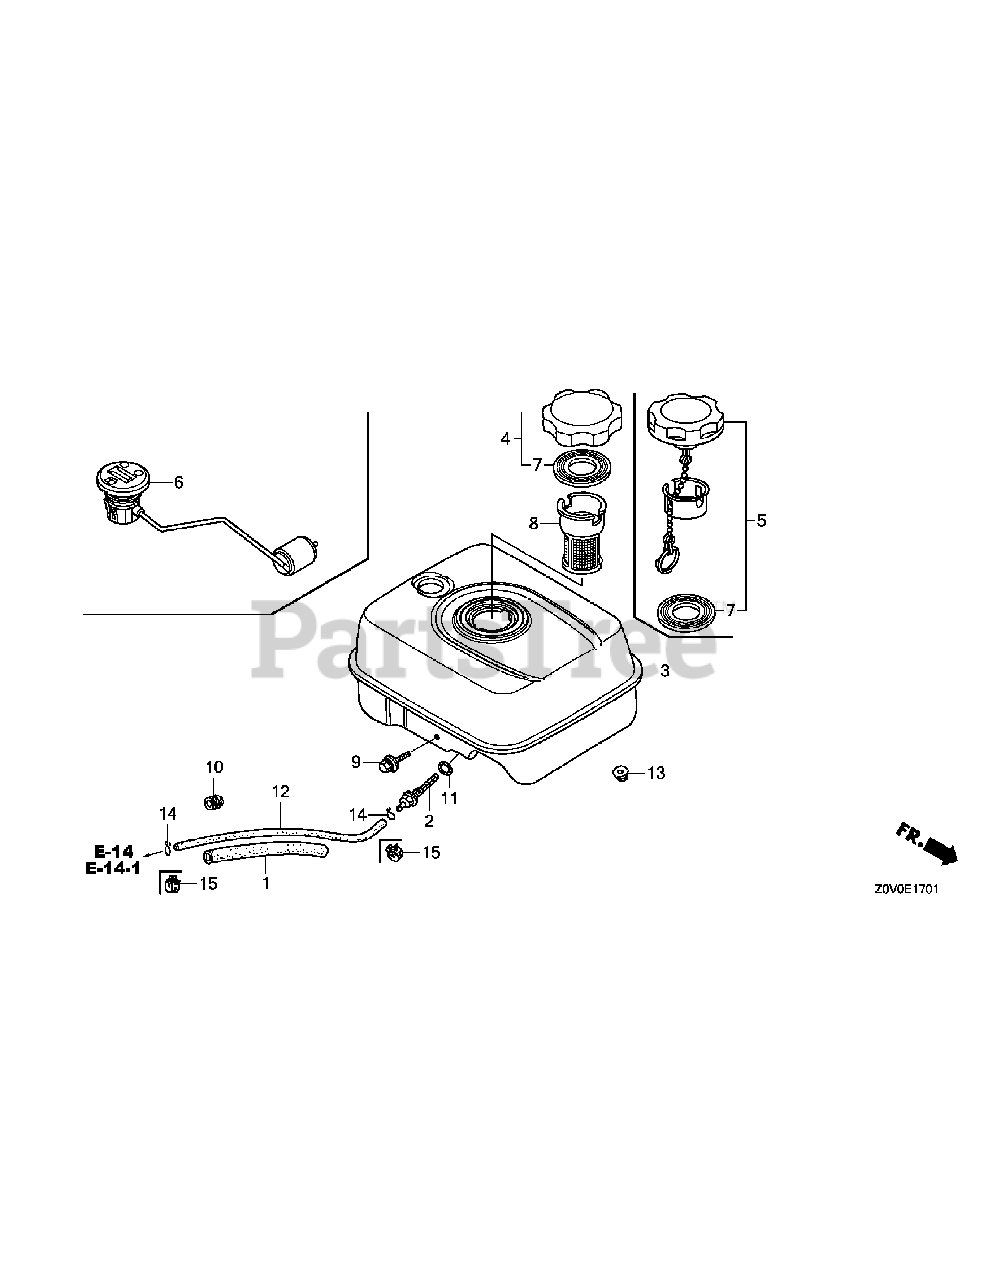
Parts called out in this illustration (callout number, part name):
1	Rubber, Supporter(107Mm)
2	Joint, Fuel Tank
3	Tank Comp., Fuel
4	Cap Comp., Fuel Filler
5	Cap Comp., Fuel Filler
6	Gauge Assy., Fuel
7	Packing, Fuel Filler Cap
8	Filter, Fuel
9	Bolt, Flange, 6X34
10	Rubber, Fuel(9X15X20)
11	O-Ring, 14Mm(Nok)
12	Tube, Fuel, 4.5X145(Fkm)
13	Nut, Flange, 6Mm
14	Clip, Tube(B8)
15	Clamp, Tube(D8)
